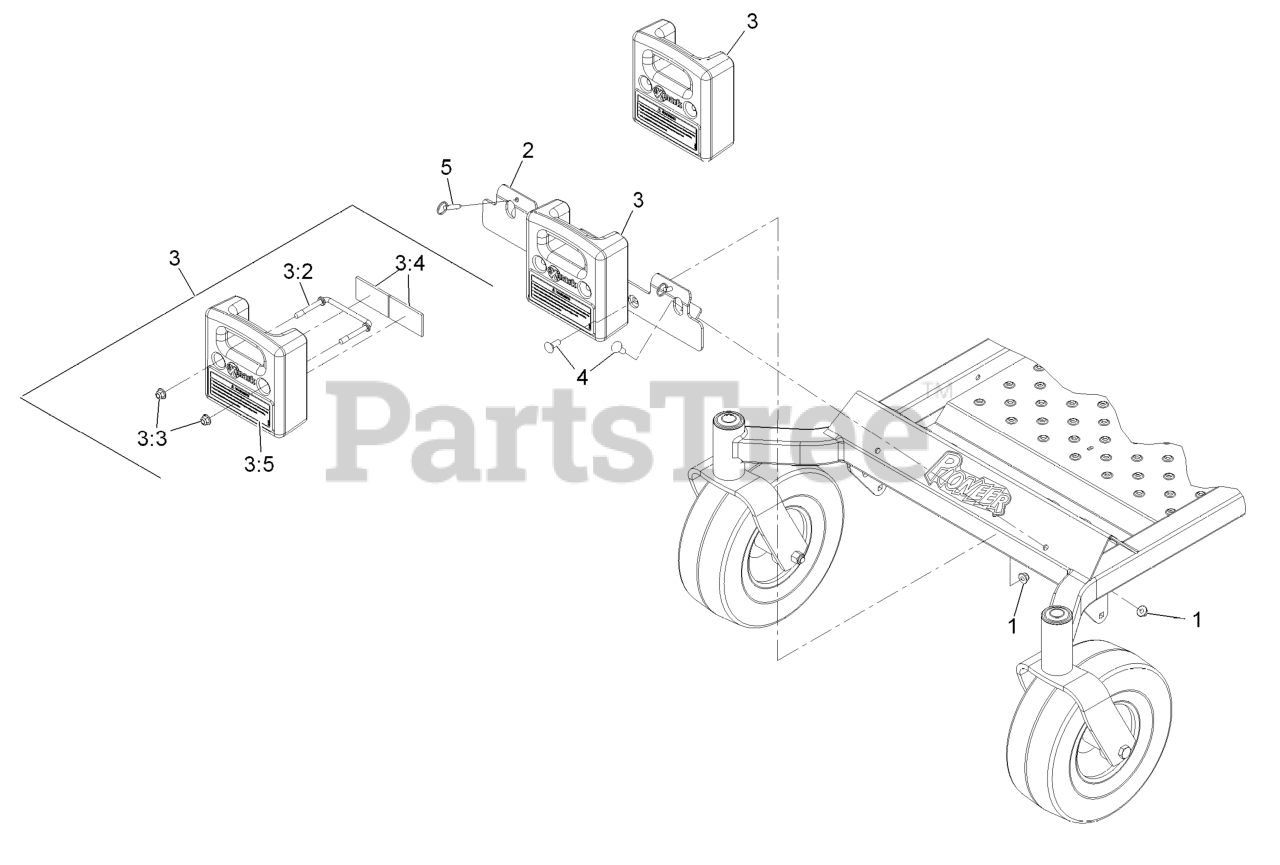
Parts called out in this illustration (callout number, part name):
1	NUT-HF, NI
2	THREE WEIGHT ASM
3	WEIGHT ASM
3:2	WIREFORM-WEIGHT
3:3	NUT-HF, NI
3:4	CUSHION-RUBBER
3:5	DECAL,WEIGHT
4	BOLT-CARR
5	PIN-BALL, DETENT
